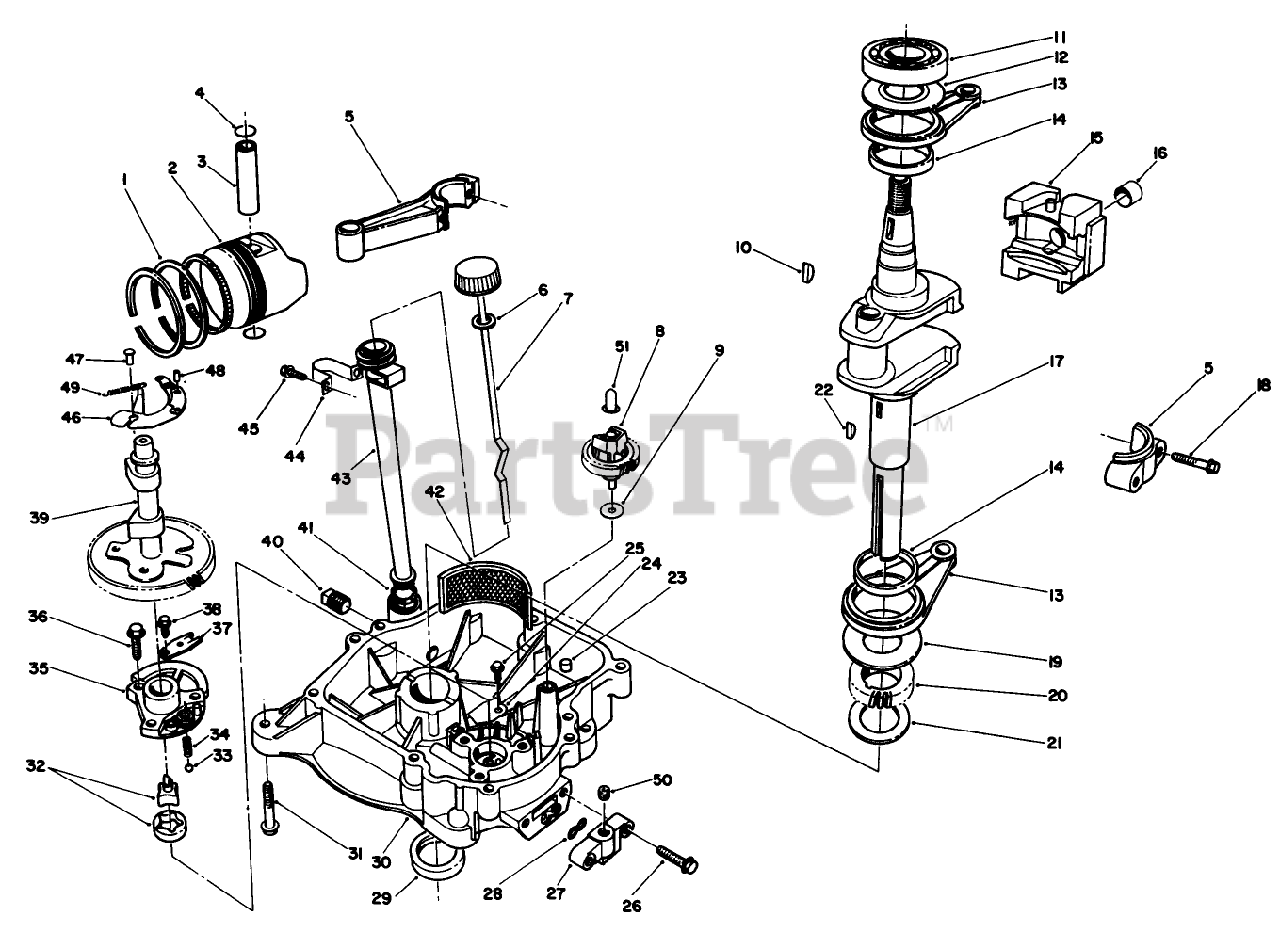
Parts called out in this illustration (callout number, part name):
1	Piston Ring Set
3	Pin-Piston
4	Ring-Snap
5	Connecting Rod Ass-y-Standard (includes item 44)
8	Governor ASM
11	Ball Bearing
13	Rod Assy (includes item 135)
14	Bearing Plane
15	Weight Complete (includes item 133)
16	Bushing
17	Crankshaft
21	Shim (1.18)
29	Oil Seal
31	Bolt-Flanged (8X45)
32	Pump ASM-Oil
35	Cover-Pump
38	BOLT-FLANGED (6X10)
39	Camshaft Compression
41	O-RING (16mm)
42	Filter-Oil
46	Decompressor
